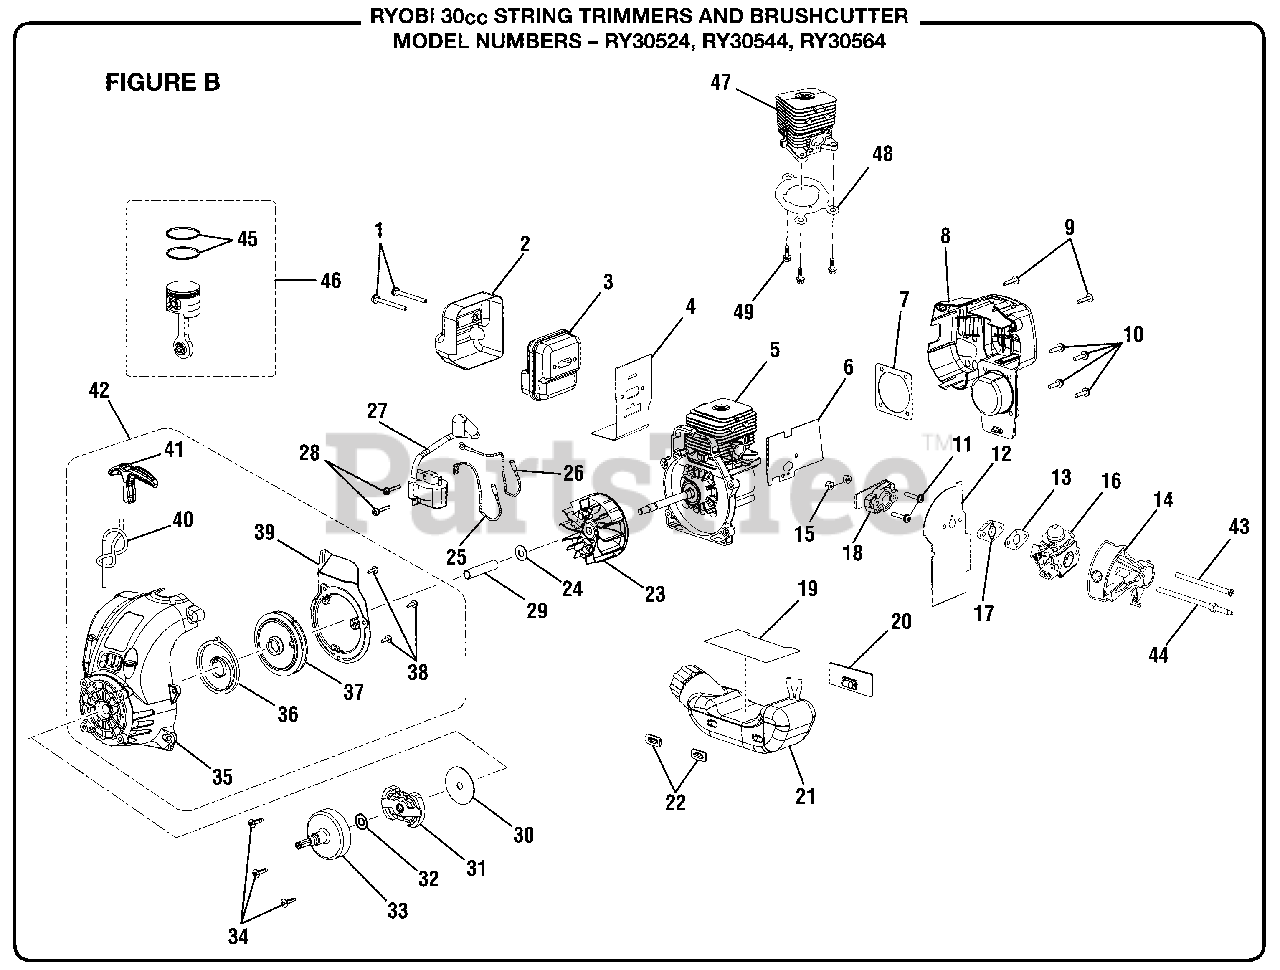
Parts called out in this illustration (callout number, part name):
1	Screw (10-24 x 2-1/8 in Torx Tr Hd.)
2	Heat Shield
3	Muffler Assembly
4	Muffler Gasket
5	Short Block Assembly (30 cc)
6	Intake Gasket
7	Cover Gasket
8	Rear Housing
9	Screw (10-14 x 7/8 in Truss Hd T.f.)
10	Screw w/Lock Washer (10-24 x 3/4 in Pan Hd Torx)
11	Screw (10-24 Pan Hd.)
12	Carburetor Gasket
13	Carburetor Gasket (Non-strato)
14	Roto-choke Base
15	Nut (M5-0.8 x 5)
16	Carburetor Assembly
17	Spacer
19	Tank Insulation Gasket
20	Rubber Bumper
21	Fuel Tank Assembly w/Cap
22	Bumper
23	Rotor w/Pawls Assembly
24	Washer
25	Lead w/Terminals
26	Lead w/Terminals
27	Ignition Module w/3 Sec Kill Switch
28	Screw (8-32 Thd Forming)
29	Spacer Tube
30	Washer (Pkg)
31	Clutch Assembly
32	Clutch Washer
33	Drum and Connector
34	Screw (10-24 x 3/4 in.)
35	Starter Housing and Eyelet Assembly
36	Spring and Container
37	Starter Pulley Assembly
38	Screw (Thread Forming)
39	Baffle/Isolator
40	Starter Rope 42 (Pkg)
41	Starter Grip
42	Starter Housing Assembly
43	Bolt (M5-0.8 x 57)
44	Double Sided Hex Bolt
45	Piston Ring
46	Piston w/Rod Assembly
47	Cylinder, 30cc
48	Cylinder Gasket
49	Screw (M5 X 20 mm)
